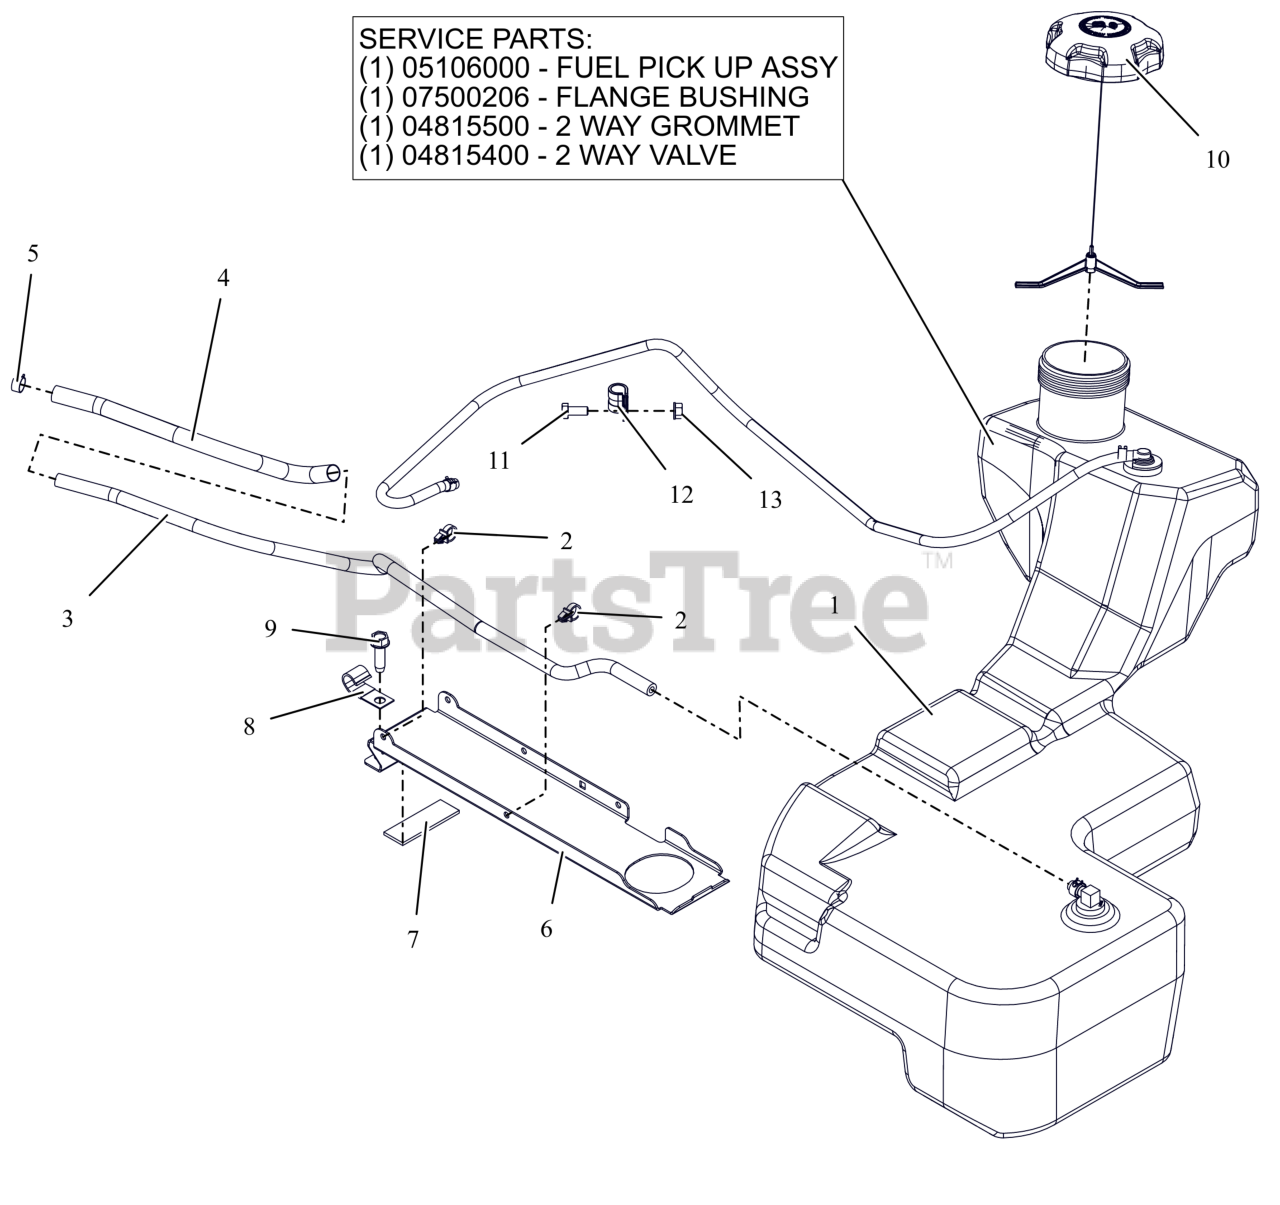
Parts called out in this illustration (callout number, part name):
1	ASM, FUEL TANK-HD
1	ASM, HD FUEL PICK-UP
1	BSHG-FLG .375X1.062X.625 NITR
1	GROMMET, 2-WAY
1	VALVE, 2-WAY
2	ROUTING CLIP (1/2" ID)
3	1 INCH OF HOSE, .25 LOW-PERM BULK GAS
4	SLEEVE, THERMAL 12"
5	CLAMP, FUEL LINE
6	BRKT, FUEL TANK HOLD DOWN
7	PAD,RBR 1.0"X3.0" W/ADHESIVE
9	SCR,TAP .375-16X1.25HWH TR ZCC
10	CAP, FUEL - 3.50 RATCHET INLET VENT
11	BLT,HEX .31-18X.75 G5 ZCC
12	CLAMP, CUSHIONED STEEL
13	NUT,LK-CTR-FLG .31-18 GF ZCC
